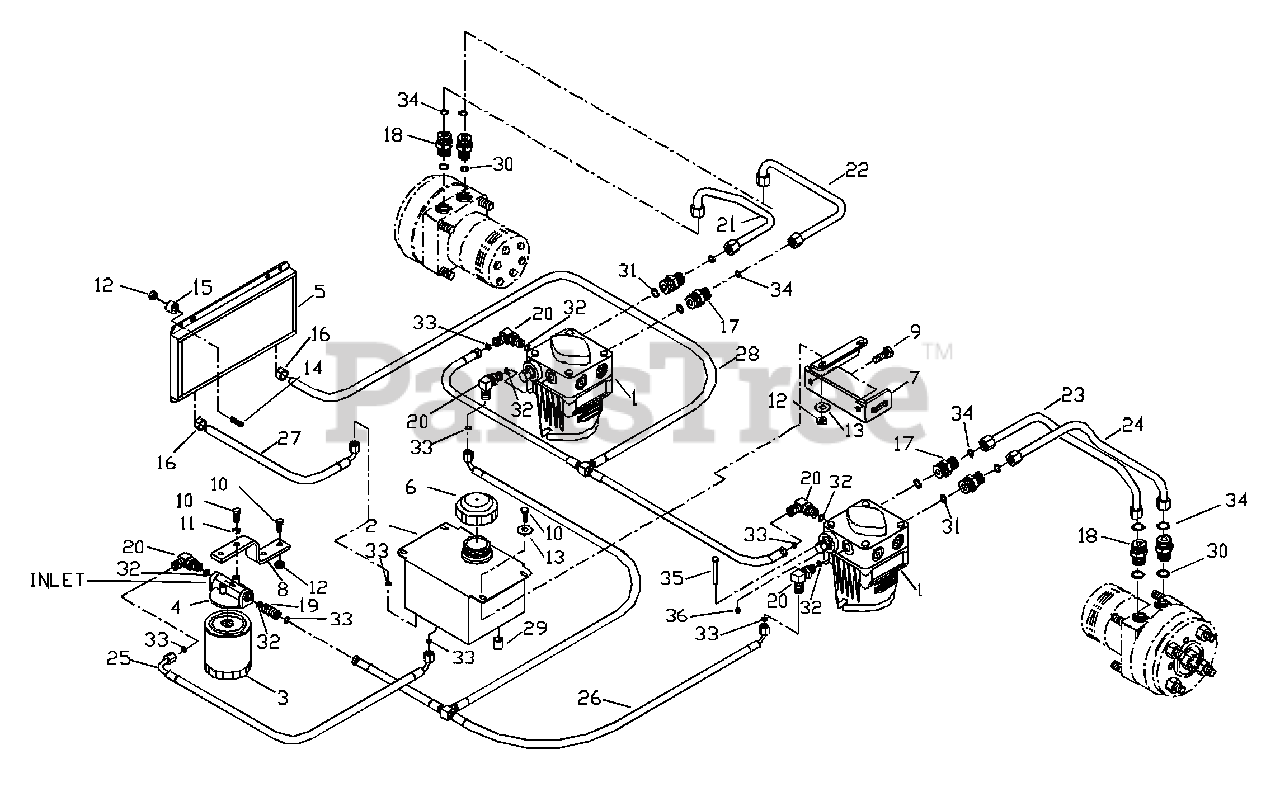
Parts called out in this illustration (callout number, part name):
1	PUMP
4	FILTER HEAD
7	TANK MOUNT LT.
7	TANK MOUNT RT.
8	FILTER BRACKET
9	HCS 5/16 X 3/4
10	HCS 1/4C X 3/4
11	1/4 LOCK WASHER
12	1/4 LOCK NUT
13	1/4 FLAT WASHER
14	HCS 1/4C X 2.25
16	HOSE CLAMP
18	STR. FITTING
21	R. OUTSIDE TUBE
22	R. INSIDE TUBE
23	L. INSIDE TUBE
24	L. OUTSIDE TUBE
30	3/4 "O" RING
31	1/2 "O" RING
32	3/8 "O" RING
33	3/8 "O" RING FLARE
34	3/8 "O" RING FLARE
35	CLEVIS PIN
